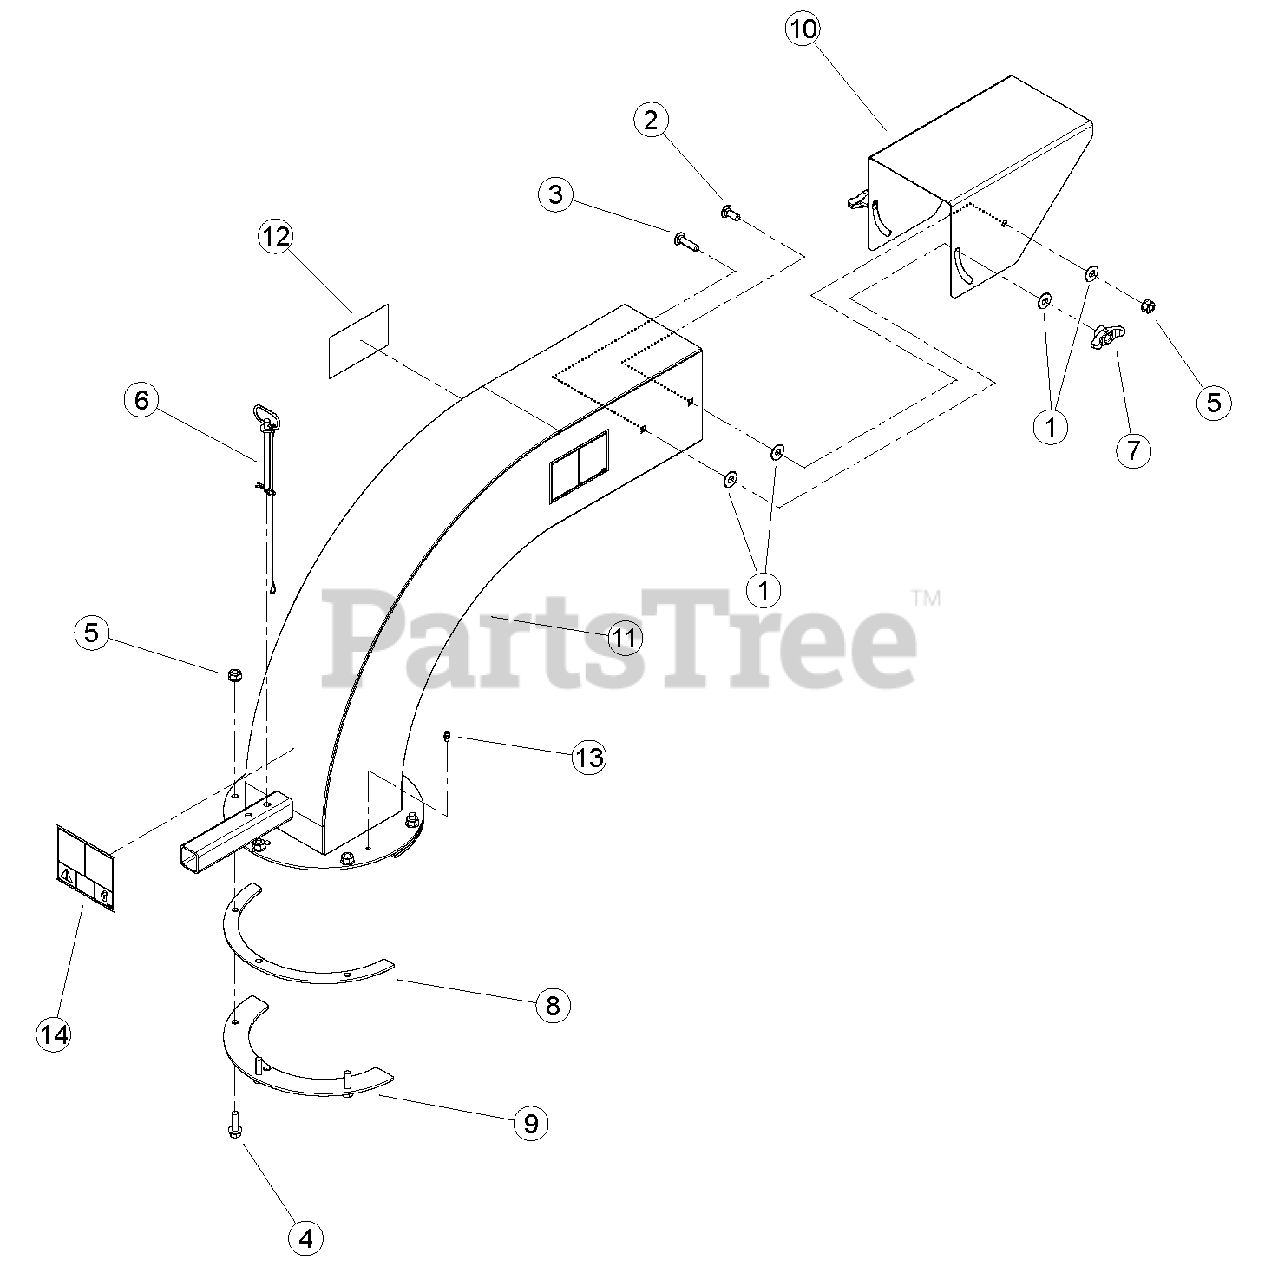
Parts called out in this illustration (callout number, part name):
1	WASHER, 3/8" FLAT ZP
2	BOLT, 3/8 X 1" GR5 CRG NC ZP
3	BOLT, 3/8 X 1-1/2" GR5 CRG NC ZP
4	BOLT, 3/8 X 1-1/4 FLANGE NC
5	NUT, 3/8-16 NYLOCK FLANGE
6	PIN, 3/8 X 4.25" DISCHARGE
7	KNOB, 3/8-16 UNC FEMALE TEE
8	RING, DISCHARGE SPACER
9	RING, DISCHARGE CLAMP
10	CAP, ORCHARD DISCHARGE
11	ASSEMBLY, ORCHARD DISCHARGE W/ DECALS
12	DECAL, DISCHARGE ISO
13	FITTING, 1/4 SELF-TAP GREASE
14	DECAL, DISCHARGE DEBRIS & LOCK
